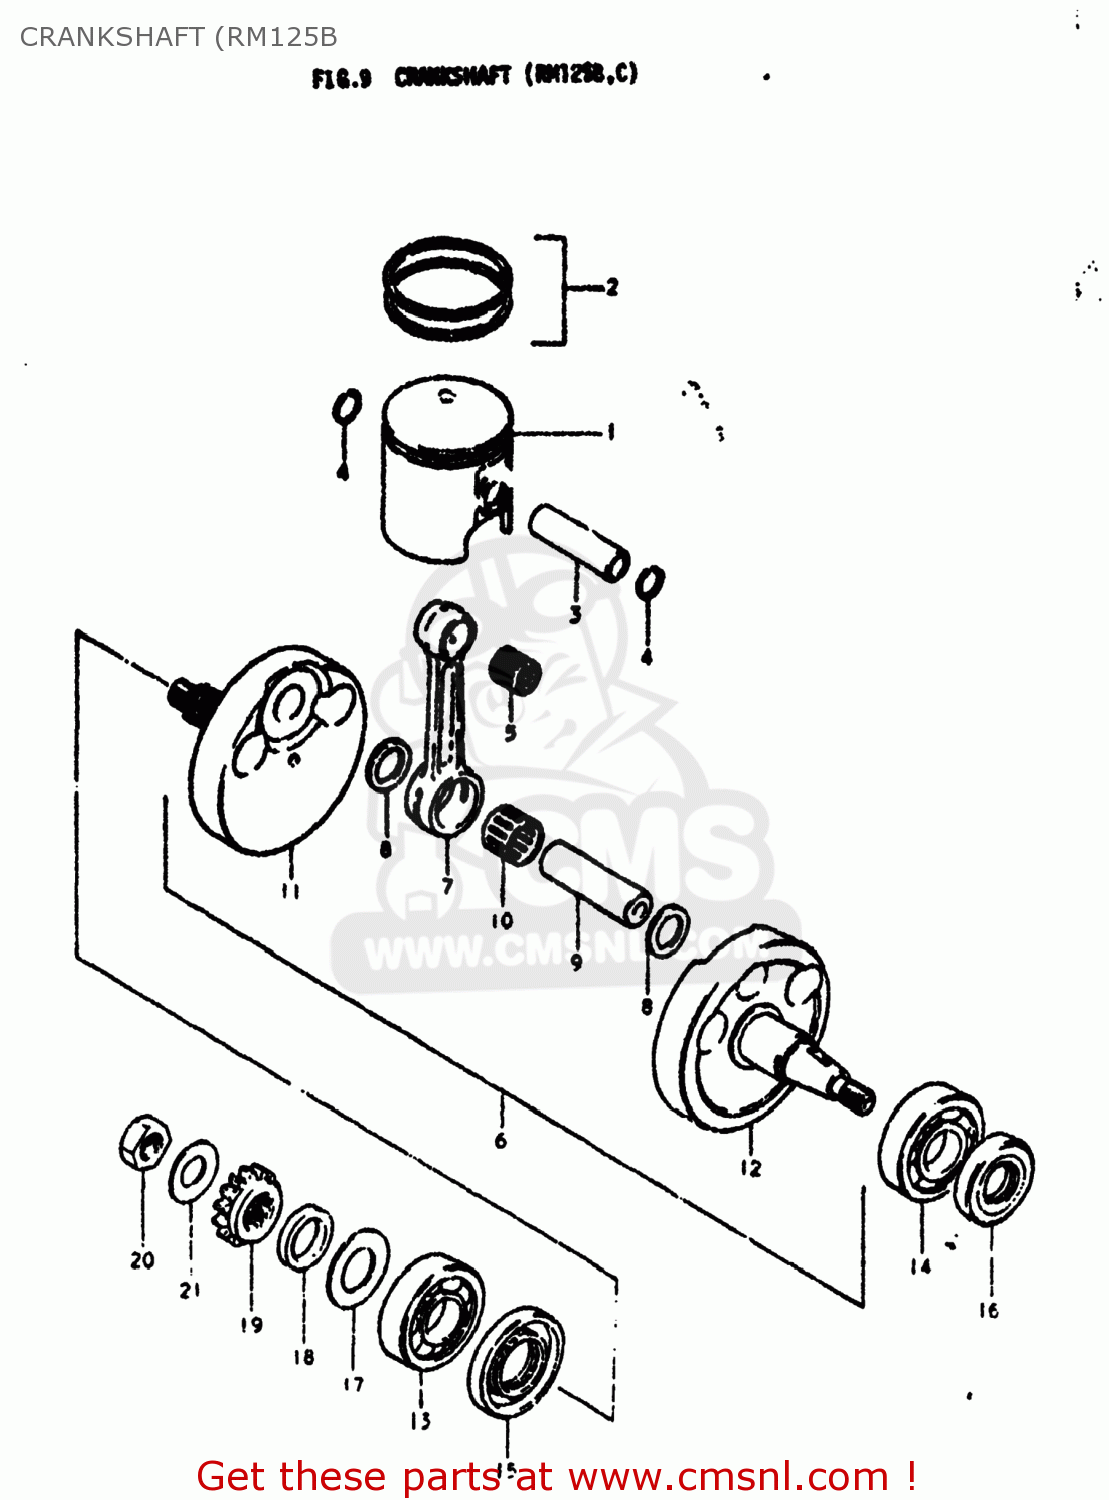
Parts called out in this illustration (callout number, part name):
1	PISTON
2	RING SET,PISTON
3	PIN,PISTON
4	RING,SNAP 14MM
5	BEARING
6	CRANKSHAFT ASSEMBLY
7	CONNECTING ROD
8	WASHER(19X32X1)
9	PIN,CRANK
10	BEARING(19X25X16)
11	CRANKSHAFT
12	CRANKSHAFT,LEFT
13	BEARING
14	BEARING
15	SEAL,OIL(30X56X9)
16	OIL SEAL
18	SPACER
19	GEAR,PRIMARY DRIVE
20	NUT
21	WASHER
